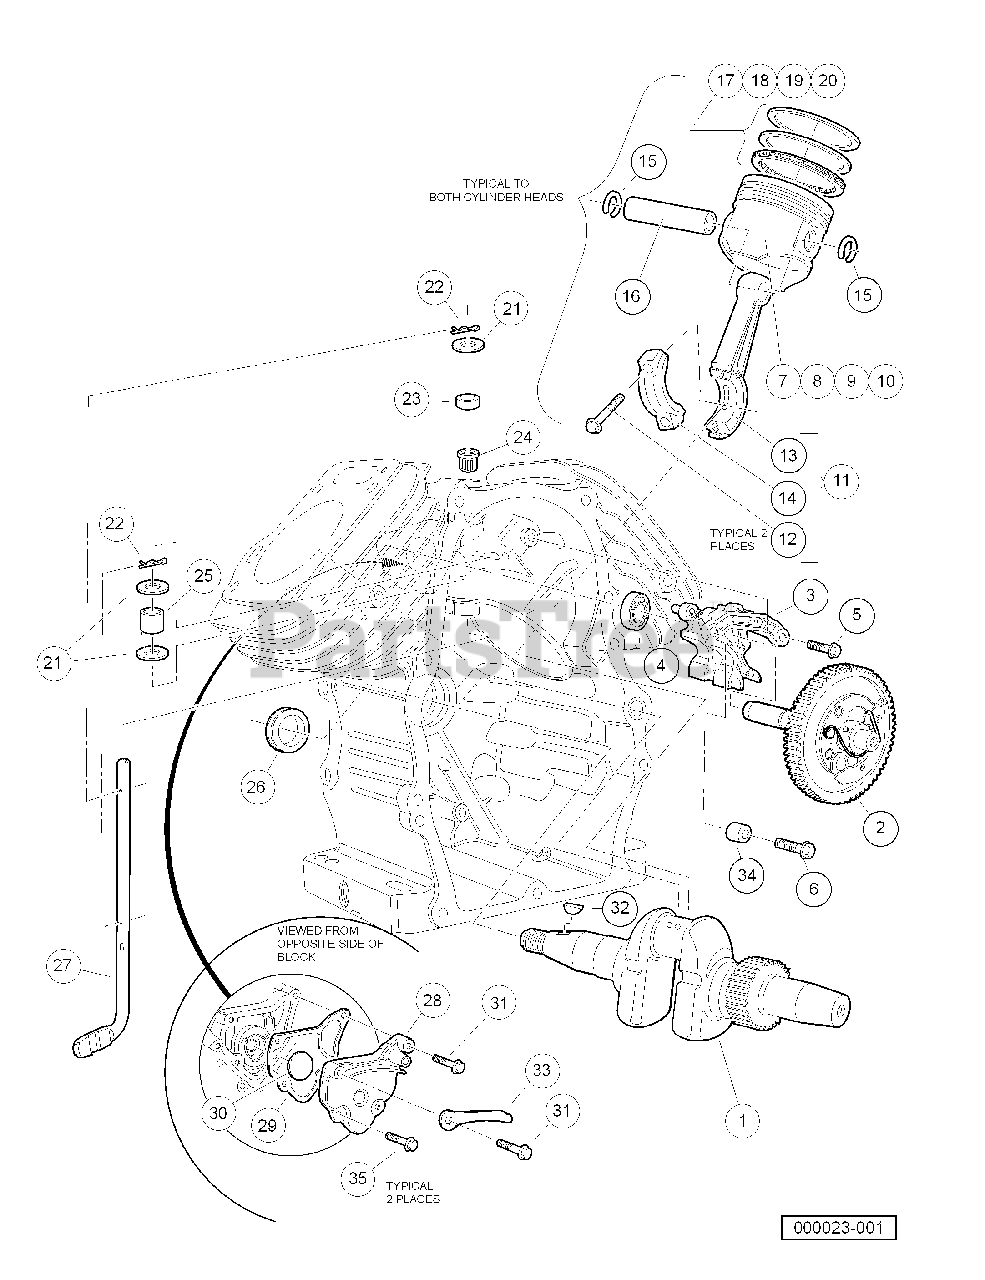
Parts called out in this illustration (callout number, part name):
1	Crankshaft
2	Camshaft Assembly
3	Lifter Assembly, Valve
4	Bearing, Radial Ball, 6003
5	Bolt, Flange Head, M5 X 1 X 16
6	Bolt, Flange Head, M6 X 1 X 25
7	Piston, Std
8	Piston, Over-Sized 0.25
9	Piston, Over-Sized 0.50
10	Piston, 0.75
11	Rod Assy., Connecting
12	Bolt, Connecting Rod, 6 X 37
13	Connecting Rod
14	Cap, Connecting Rod
15	Clip, Piston Pin, 18mm
16	Pin, Piston
17	Ring Set, Piston, Std
18	Ring Set, Piston, OS 0.25
19	Ring Set, Piston, OS 0.50
20	Ring Set, Piston, OS 0.75
21	Washer, Plain, M8
22	Pin, Lock, 8 Mm
23	Bearing, Needle, 8 X 12.7 X 11
24	Oil Seal, 8 X 14 X 5
25	Bearing, Needle, 8 X 12 X 10
26	Oil Seal, 38 X 58 X 9
27	Shaft, Governor Arm
28	Cover, Breather
29	Gasket, Breather Cover
30	Valve, Breather
31	Bolt, Flange Head, M6 X 1 X 32
32	Key, Special Woodruff, 25 X 18
33	Clamp, Wire
34	Pin A, Dowel
35	Bolt, Flange Head, 6 X 16
